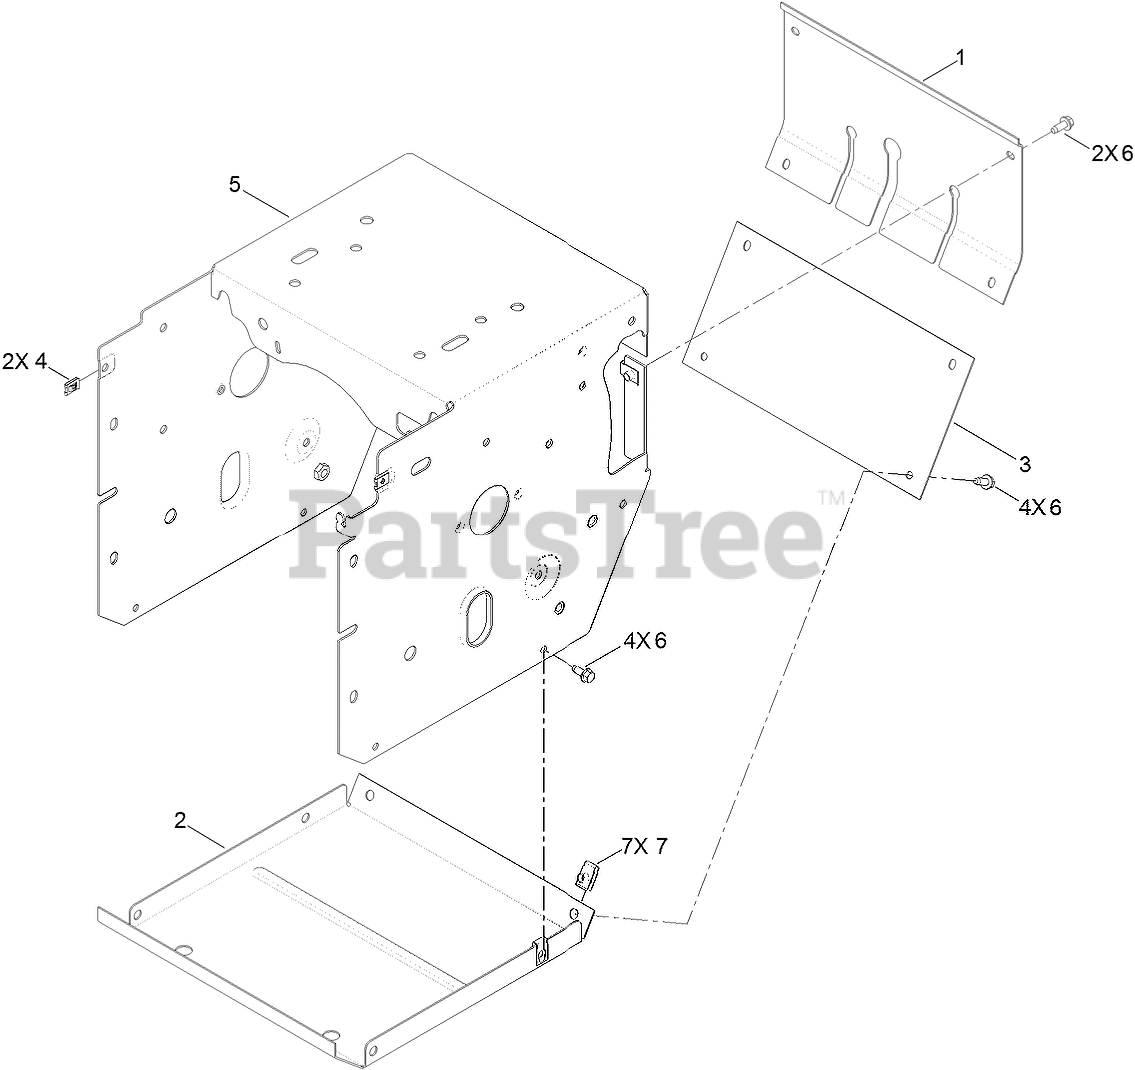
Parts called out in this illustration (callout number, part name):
1	COVER-UPPER
2	PAN-BOTTOM
3	COVER-LOWER
4	NUT-SPEED, U-TYPE
5	FRAME-TRACTION
6	SCREW-HWH
